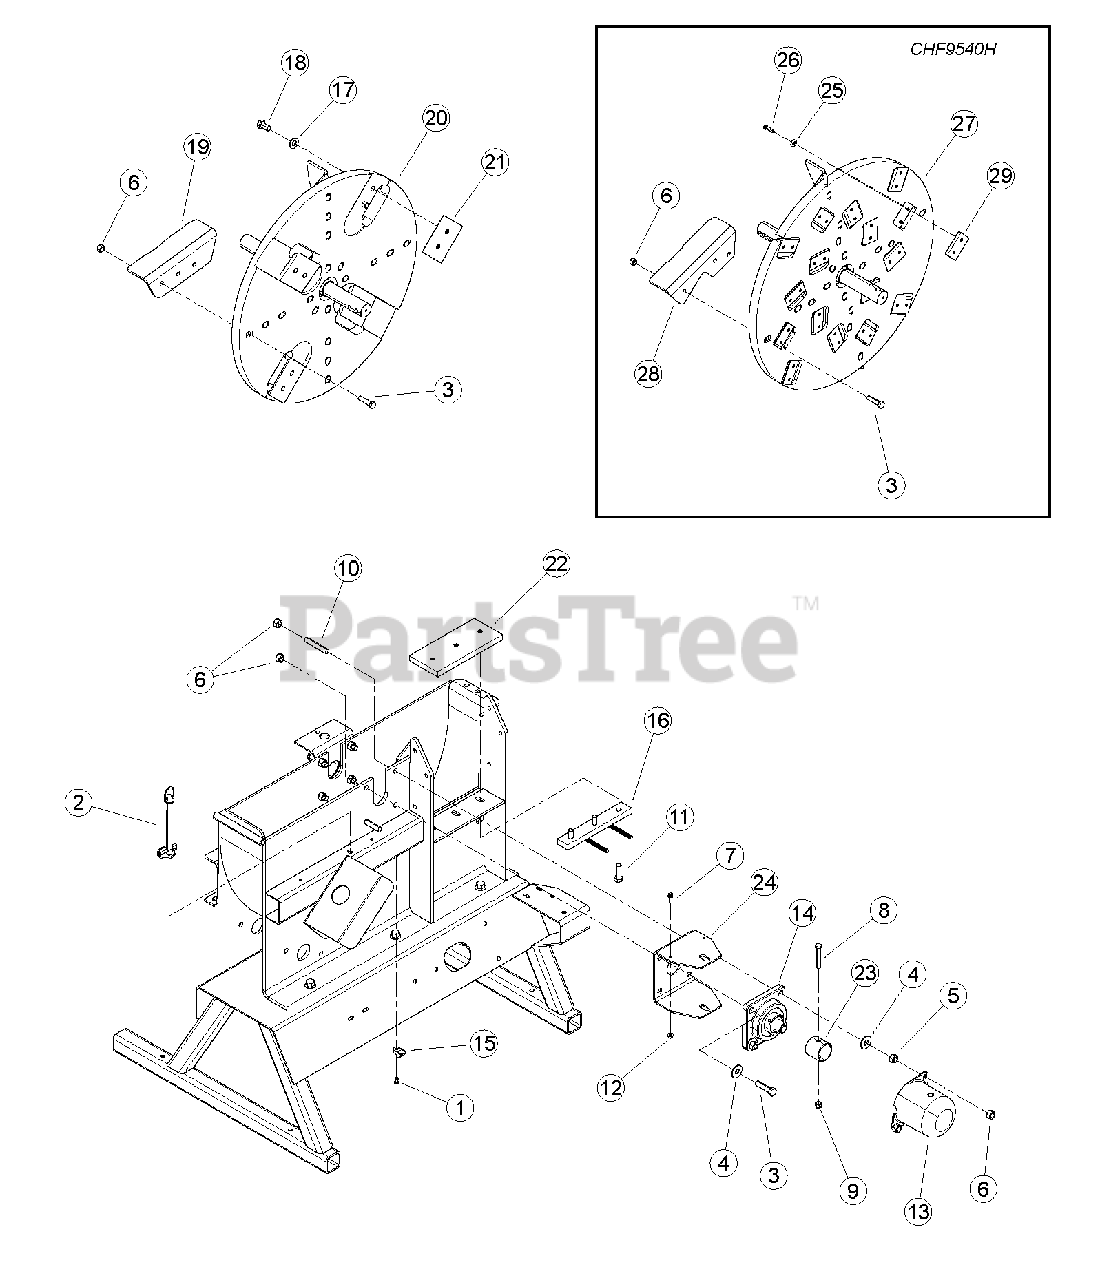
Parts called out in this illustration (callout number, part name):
1	RIVET, 1/4 X 3/4 ST POP
2	PIN, HITCH 1/2 X 6-1/2 W LYNCH
3	BOLT, 1/2 X 2 GR5 HEX CAPSCREW ZP
4	WASHER, 1/2" FLAT ZP
5	NUT, 1/2" HEX NC ZP
6	NUT, 1/2" CENTERLOCK GRB ZP
7	BOLT, 1/4-20 X 3/4 HWH GR5 CZP
8	BOLT, 3/8 X 2-1/2 GR5 HHCS ZP
9	NUT, 3/8" NE NYLOCK ZP
10	STUD, 1/2"-13 X 3" LG B7 ZP
11	BOLT, 1/2 X 1-1/2 GR8 NC ZP HEX HD
12	NUT, 1/4-20 NYLOCK-FLANGE
13	CAP, LARGE SHAFT
14	BEARING, 1-3/4 4 BOLT FLANGE
15	CLAMP, CABLE MOUNT
16	WELDMENT, BLOCK ADJUSTOR
17	WASHER, 5/8 SAE HARDENED
18	BOLT, M16 X 2.0 X 30 HEX HD W/PATCH
19	KIT, BIG CHIPPER FORMED PADDLES
20	ASSEMBLY, 9 INCH CHIPPER ROTOR
21	KIT, CHIPPER BLADE
22	PLATE, CHIPPER BOTTOM
23	COLLAR, CHIPPER LOCK
24	BRACKET, ROTOR LOCK
